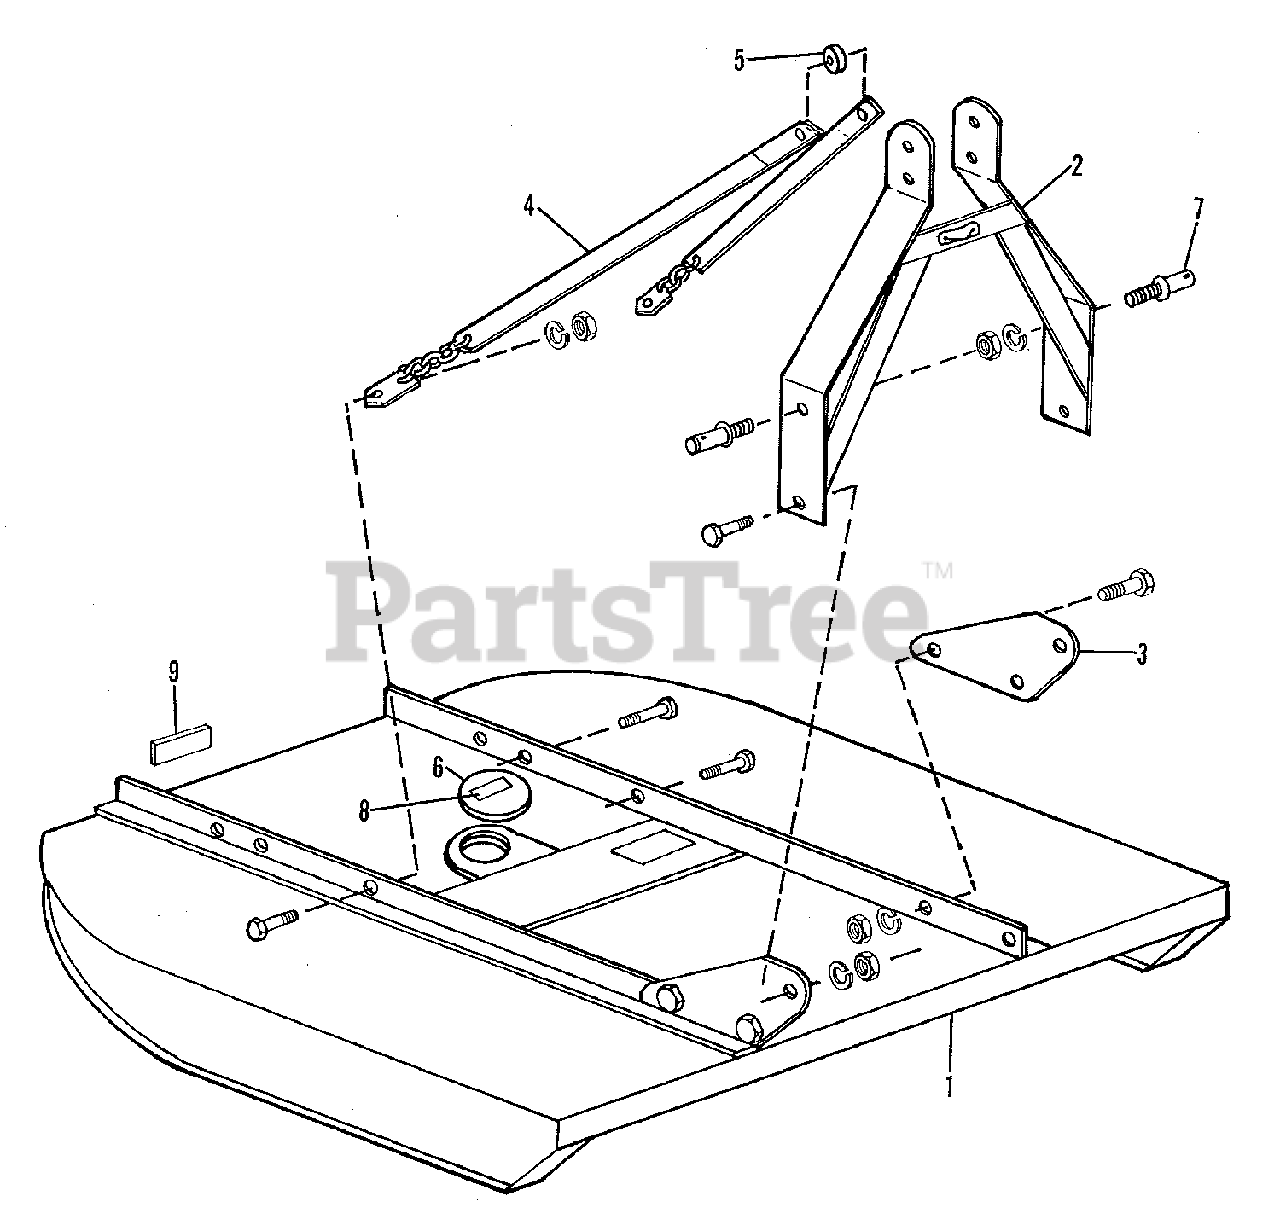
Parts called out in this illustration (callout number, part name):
1	DECK ASSEMBLY
2	FRAME ASSEMBLY, Hitch
3	CLEAT, Attaching
3	CAPSCREW, 5/8NC x 2
3	LOCKWASHER, 5/8
4	ARM ASSEMBL
4	CAPSCREW, 5/8NC x 2
4	CAPSCREW, 5/8NC x 4
4	LOCKWASHER, 5/8
5	SPACER, Arm
6	PLATE, Access
6	CAPSCREW, 1/2NC x 2
6	LOCKWASHER, 1/2
7	PIN, Link (Cat. l)
7	LOCKWASHER, 7/8
8	DECAL, Warning (Cover Position)
9	DECAL, Warning (Power, Movement & Clearance)
